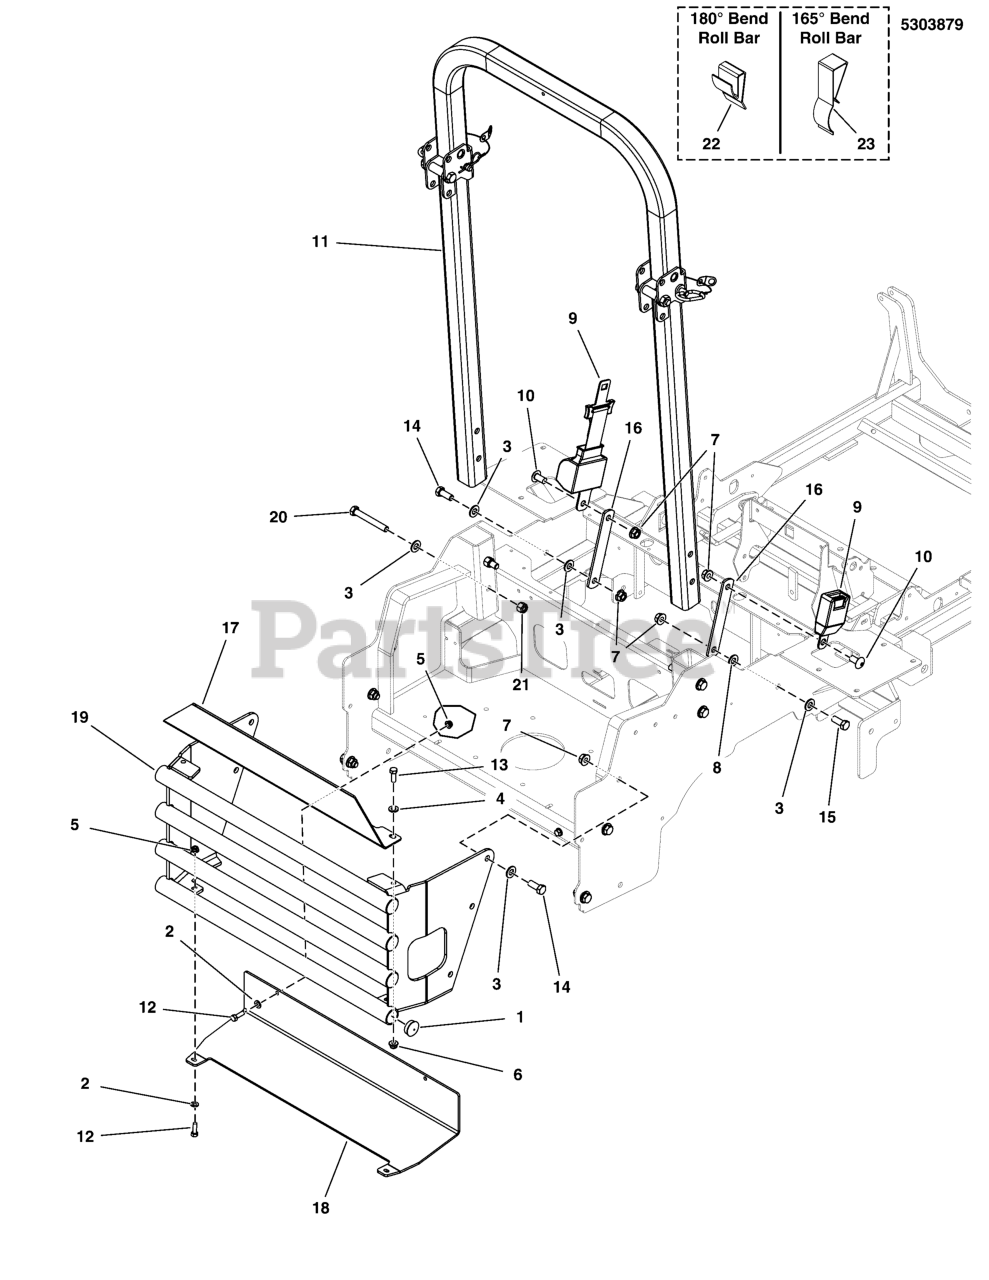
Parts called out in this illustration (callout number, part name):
1	PLUG, PANEL, 1.25 - BLACK
2	WASHER, 5/16" SAE
3	WASHER, 1/2 SAE
4	WASHER, 3/8 GD.9 FLAT
5	NUT, 5/16-18 HEX NYLOCK FLANGE
6	NUT, 3/8-16 HEX NYLOCK FLANGE
7	NUT, Hex Flange, Nylock, 1/2-13
8	SPACER, .52 X 1.00 X .38, CZ
9	SEAT BELT, RETRACTING - ASSM
10	SCREW, 1/2-13 X 1.00, SHCS
12	BOLT, 5/16-18 X 1 GD5 CZ
13	BOLT, 3/8-16 X 1" GD5 CZ
14	BOLT, 1/2-13 X 1-1/4 GD5 CZ
15	BOLT, 1/2-13 X 1-1/2 GD5 CZ
16	BAR, MOUNT, SEAT BELT, IS700Z - BLK
17	PLATE, CARB PROTECTOR - RED
18	PLATE, HEAT SHIELD, IS3200 - BLK
19	WELD, BUMPER, IS3200Z - RED
20	BOLT, 1/2-13 X 3" GD5 CZ
21	NUT, 1/2-13 HEX SIDE LOCK
22	ANTI-RATTLE SPRING, FEMCO #230328972 (SV)
23	ANTI-RATTLE SPRING, ROPS, 165 DEGREE (SV)
